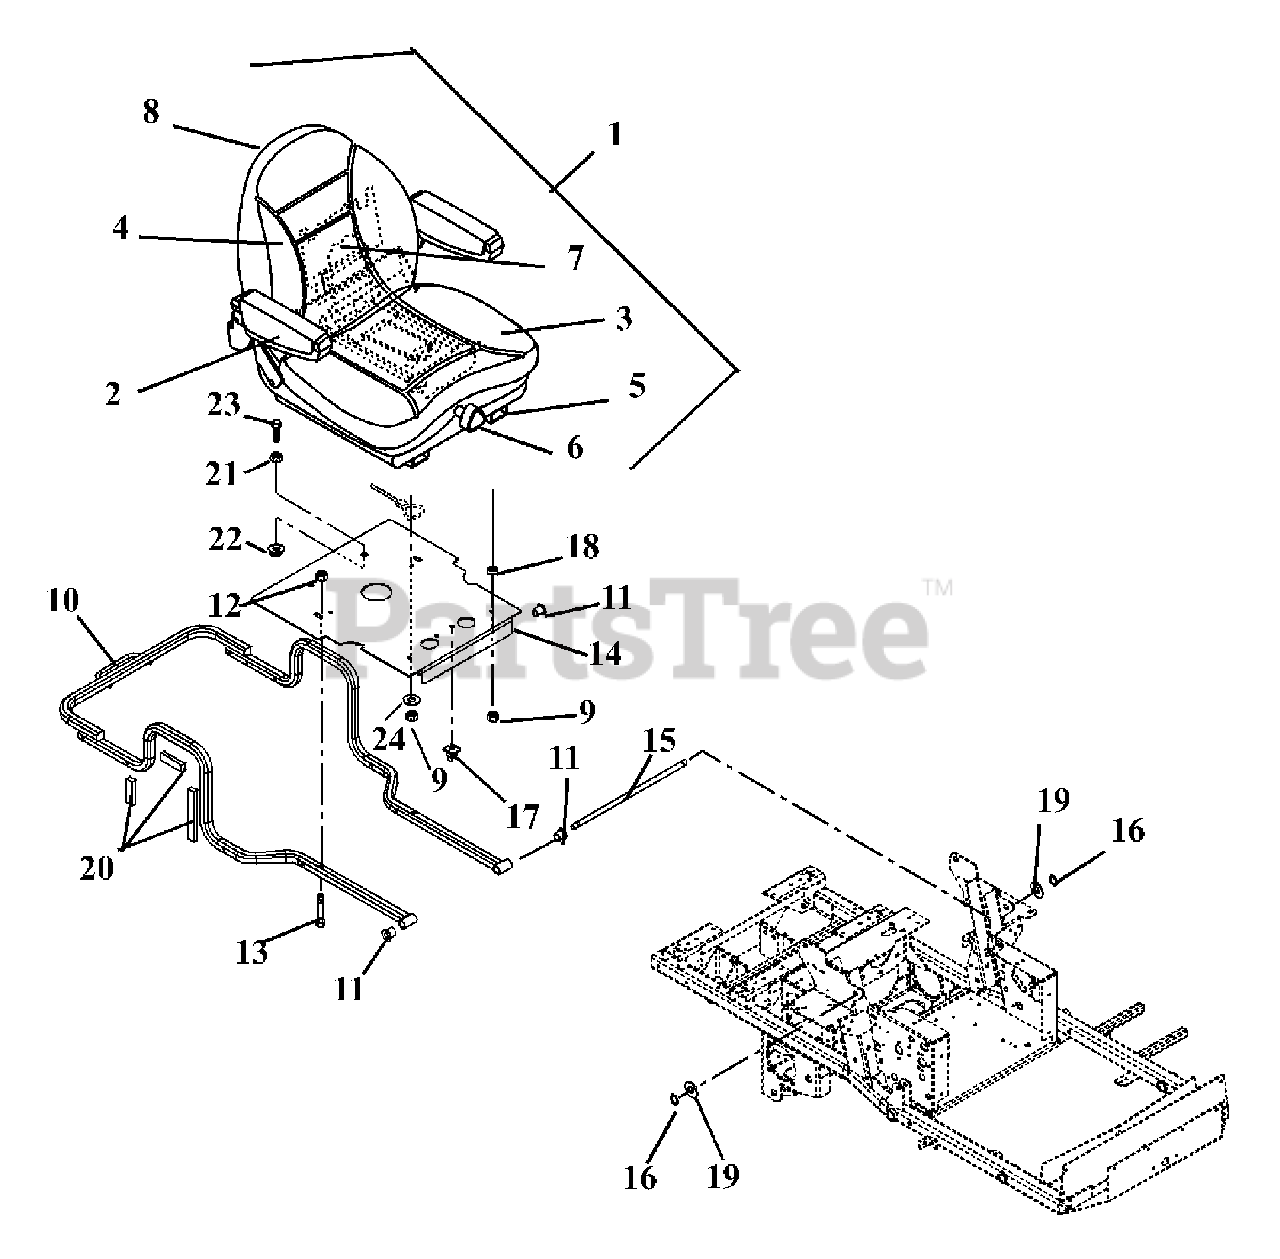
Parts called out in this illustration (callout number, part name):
1	SEAT,
2	KIT,ARMREST PAD ONLY 1 PER KIT
3	KIT,SEAT CUSHION
4	KIT,BACK CUSHION
5	KIT-SEAT SLIDE
6	KIT-SEAT KNOB
7	KIT-SPRING AND SADDLE
8	KIT-SEAT BACK PANEL
9	@NUT-LK-TOP-FLG .31-18 YWZC
10	WMT, HOOD FRAME
11	BSHG-FLG .515X.750X.745X1.00NY
12	@NUT-LK-TOP-FLG .38-16 YWZC
13	BLT, .38-16X1.50 RIB NECK YWZC
14	WMT, SEAT PIVOT MOUNT
15	ROD - SEAT FRAME PIVOT
16	RG-RTNG-EXT .500X.050 (SNAP)
17	CLIP-.38
18	BSHG-SLV .377X.624X.235
19	@WSHR-FL-STL.531X1.06X.095YWZC
20	VHB TAPE 4941F
21	@NUT-HEX .50-13 YWZC
22	@NUT-LK-TOP-FLG .50-13 YWZC
23	@BLT-HEX .50-13X1.50 GR5 YWZC
24	WSHR-FL-STL .344X1.125X.135
